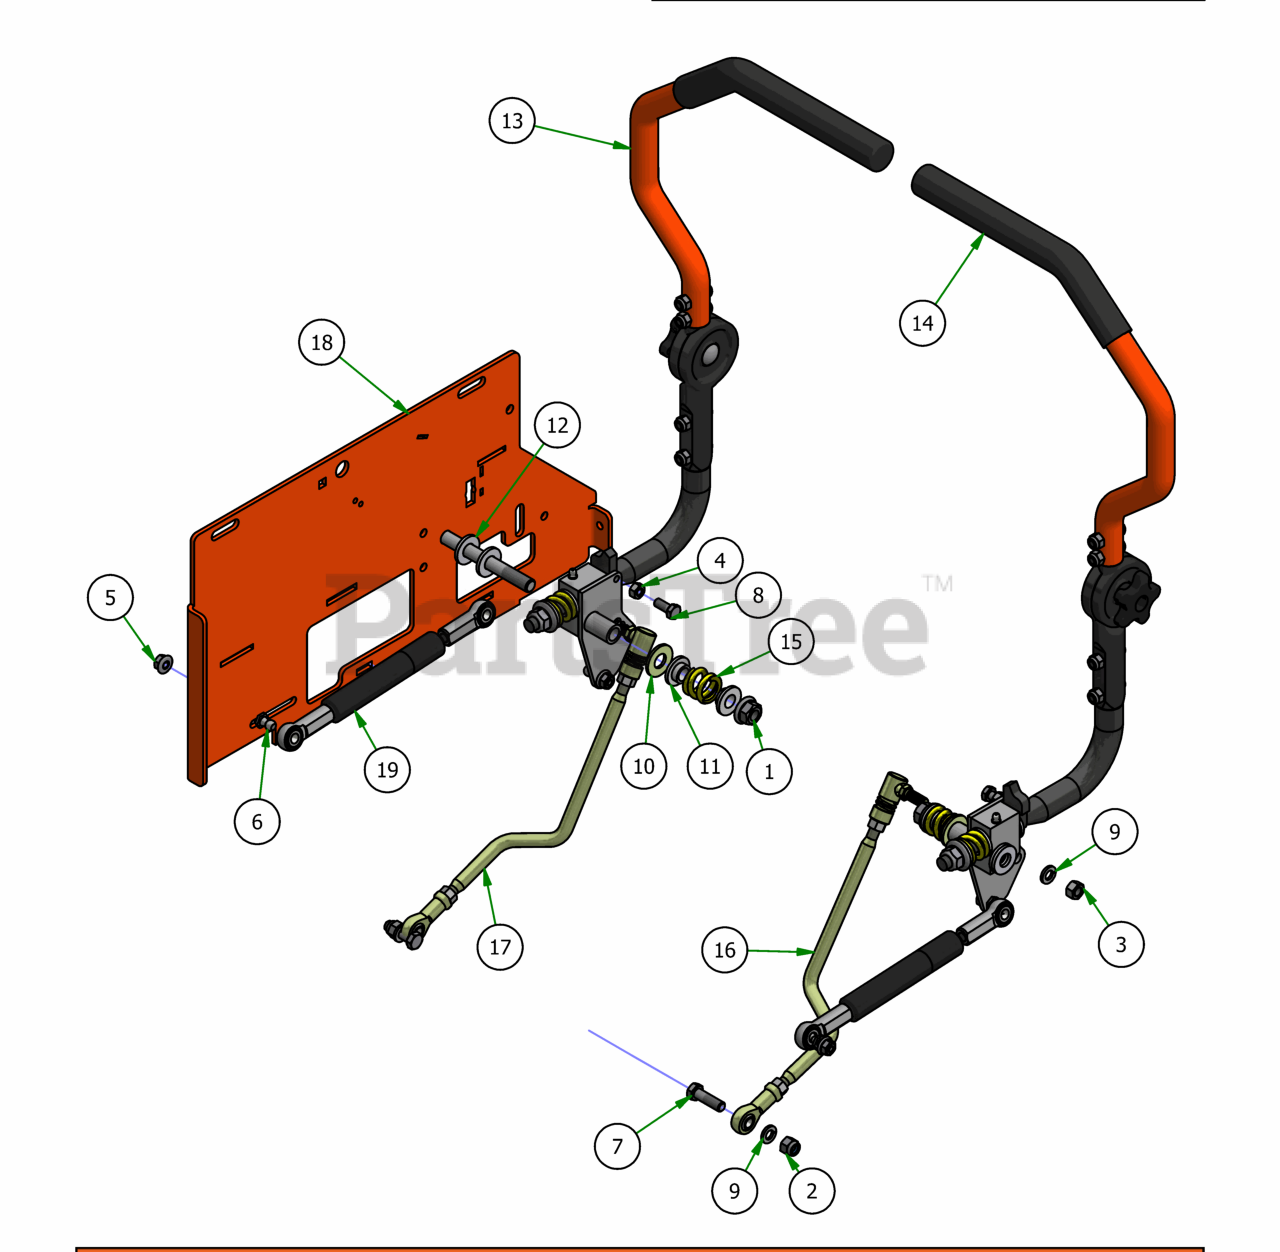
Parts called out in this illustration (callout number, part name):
1	1/2-13 Mechanical Lock Nut
2	3/8 Nylock Nut
3	3/8" Fine Threaded Jam Nut
5	5/16" Flange Nut
6	10mm Damper Ball Stud-Steering
7	3/8" x 1 1/4" Hex Bolt
8	5/16" x 3/4" Hex Bolt
9	3/8" Lock Washer
10	1/2" Washer (Grade 8)
11	.515 ID Nylon Shoulder Washer
12	.505 Nylon Spacer
13	2018 Steering Arm Assembly-Left
14	2018 Steering Arm Assembly-Right
15	Drive Lever Spring
16	Push Rod-Right
17	Push Rod-Left
18	2018 Compact Outlaw Frame
19	Steering Damper
